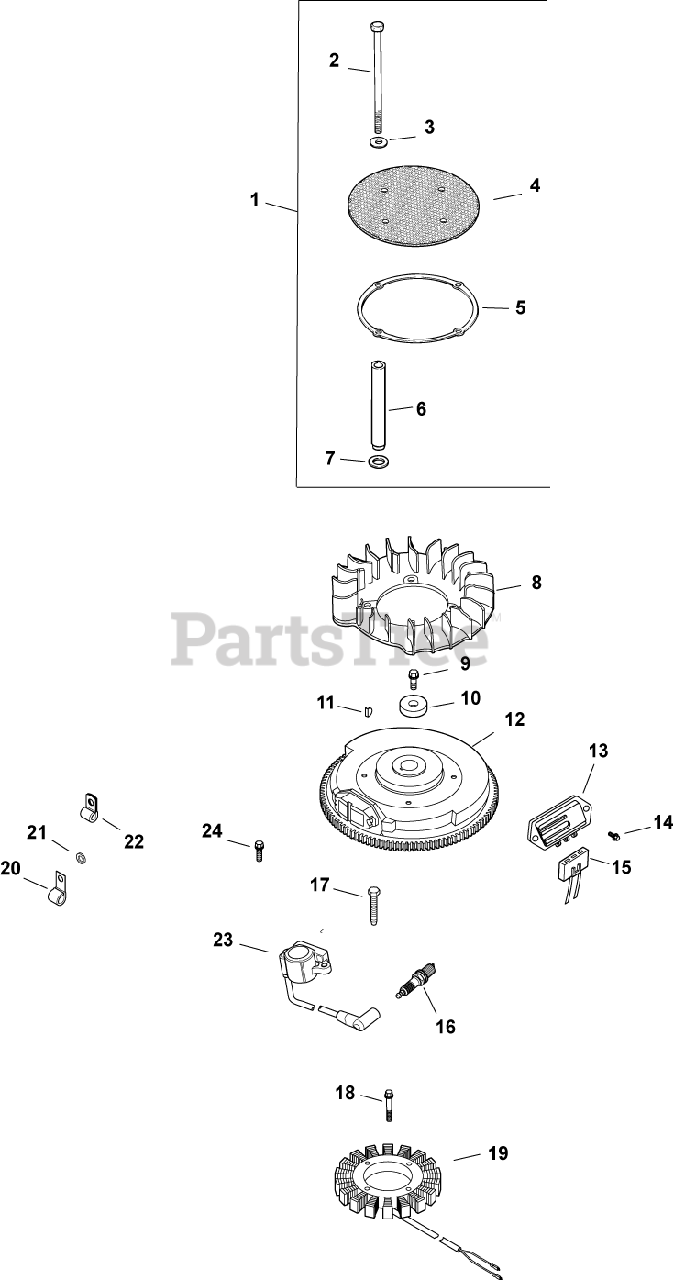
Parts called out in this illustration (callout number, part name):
1	KIT, CHOPPER SCREEN
2	SCREW, CAP M6X1.0X99.5
3	WASHER, FLAT 1/4" (O.D. 5/8")
4	SCREEN, GRASS
5	RING, SUPPORT USE 25 141 08-S
7	WASHER, SPRING 10 MM
9	SCREW, FLG M10X1.5X45 - (#25086361S)
10	WASHER, FLAT 13/32"
11	KEY, 3/16" X 5/8"
12	FLYWHEEL ASSEMBLY (LW)-USE 24 025 58-S
13	REG/RECT-15 AMP (KM)-USE 41 403 10-S
14	SCREW, PHL HD #11-16X7/8"
15	CONNECTOR, BODY (KM)-USE 25 155 41-S
16	SPARK PLUG - USE Champion RJ19LM
17	SCREW, M5X0.8X25 - (#25086402S)
18	SCREW, SKT SET #10-24X1/4"
19	KIT, 15 / 20 AMP STATOR
20	CLIP, CABLE
21	WASHER, FLAT 1/4" (O.D. 1/2")
22	CLIP, TUBE & WIRING (KM)
23	MODULE, IGNITION
24	SCREW, FLG THD FRM M5X.8X20-(#25086399S)
2458452-S	MODULE, SPARK ADV -USE 24 584 89-S
24176127-S	HARNESS, WIRING-USE 24 176 185-S
